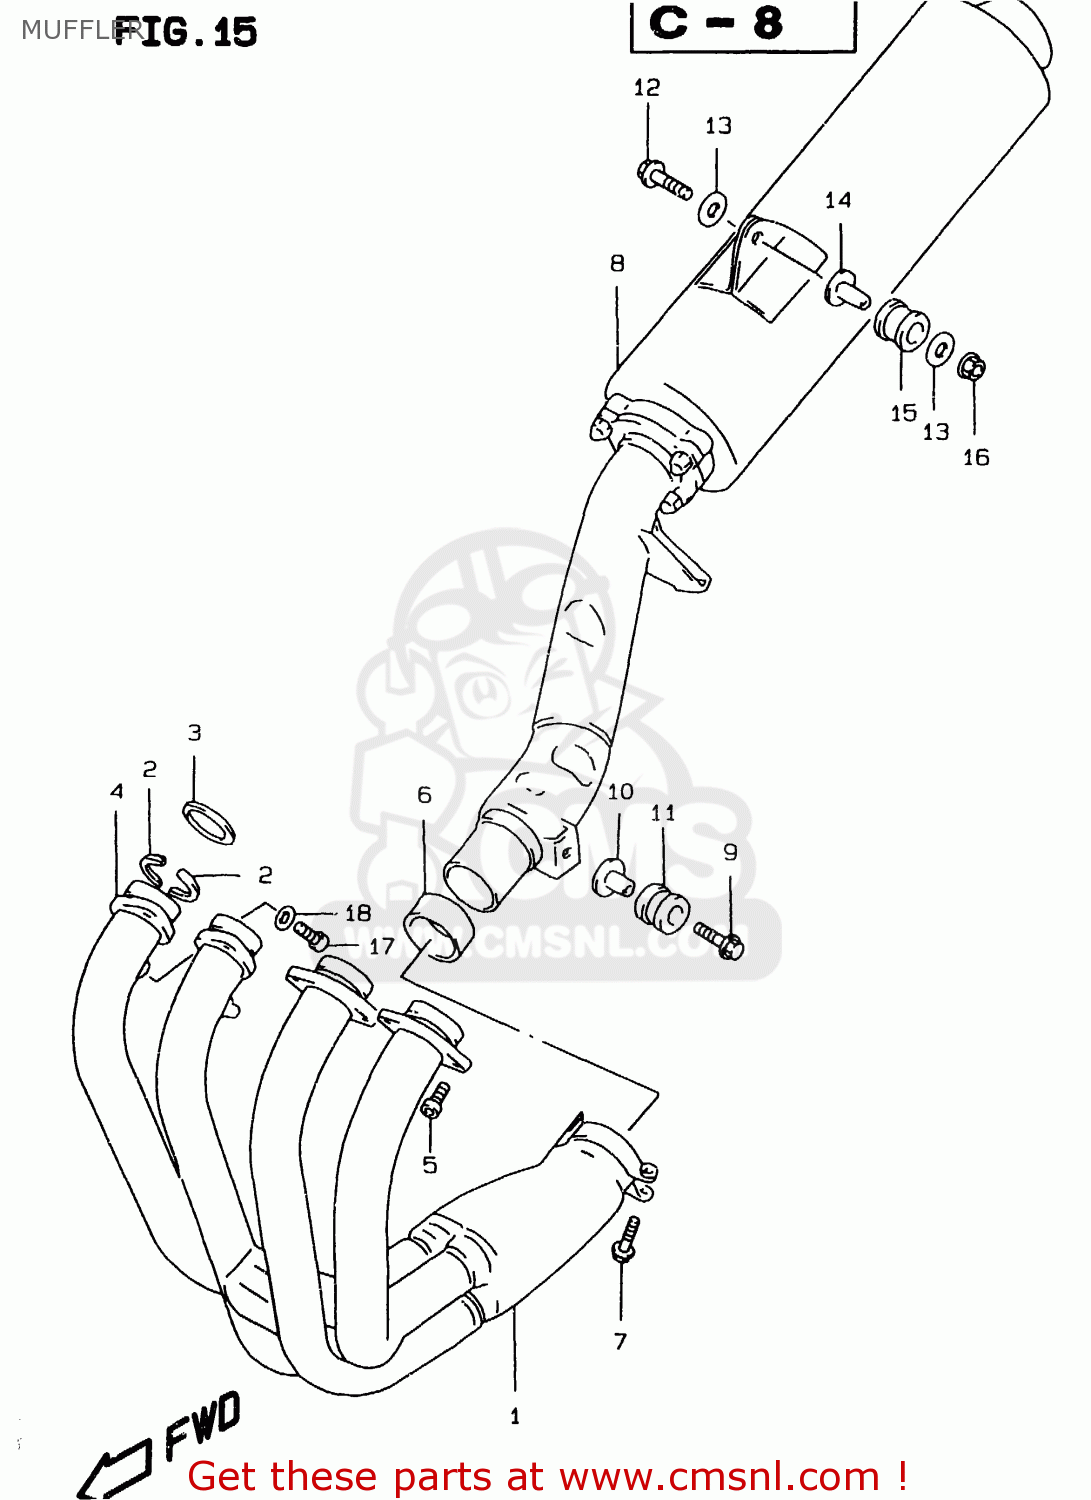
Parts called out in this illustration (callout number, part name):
1	EXHAUST
2	PLATE,EXHAUST PIPE
3	GASKET,EXHAUST (NAS)
4	CLAMP,EXHAUST PIPE
5	BOLT
6	CONNECTOR,MUFFLER
7	BOLT
8	BODY,MUFFLER
9	BOLT 8X40
10	SPACER(8.6X12X24.2)
11	CUSHION
12	BOLT
13	WASHER (8.1X33X1.6)
14	SPACER(8.6X12X27.1)
15	CUSHION
16	NUT
17	BOLT(6X10)
18	WASHER(7X12X1)
